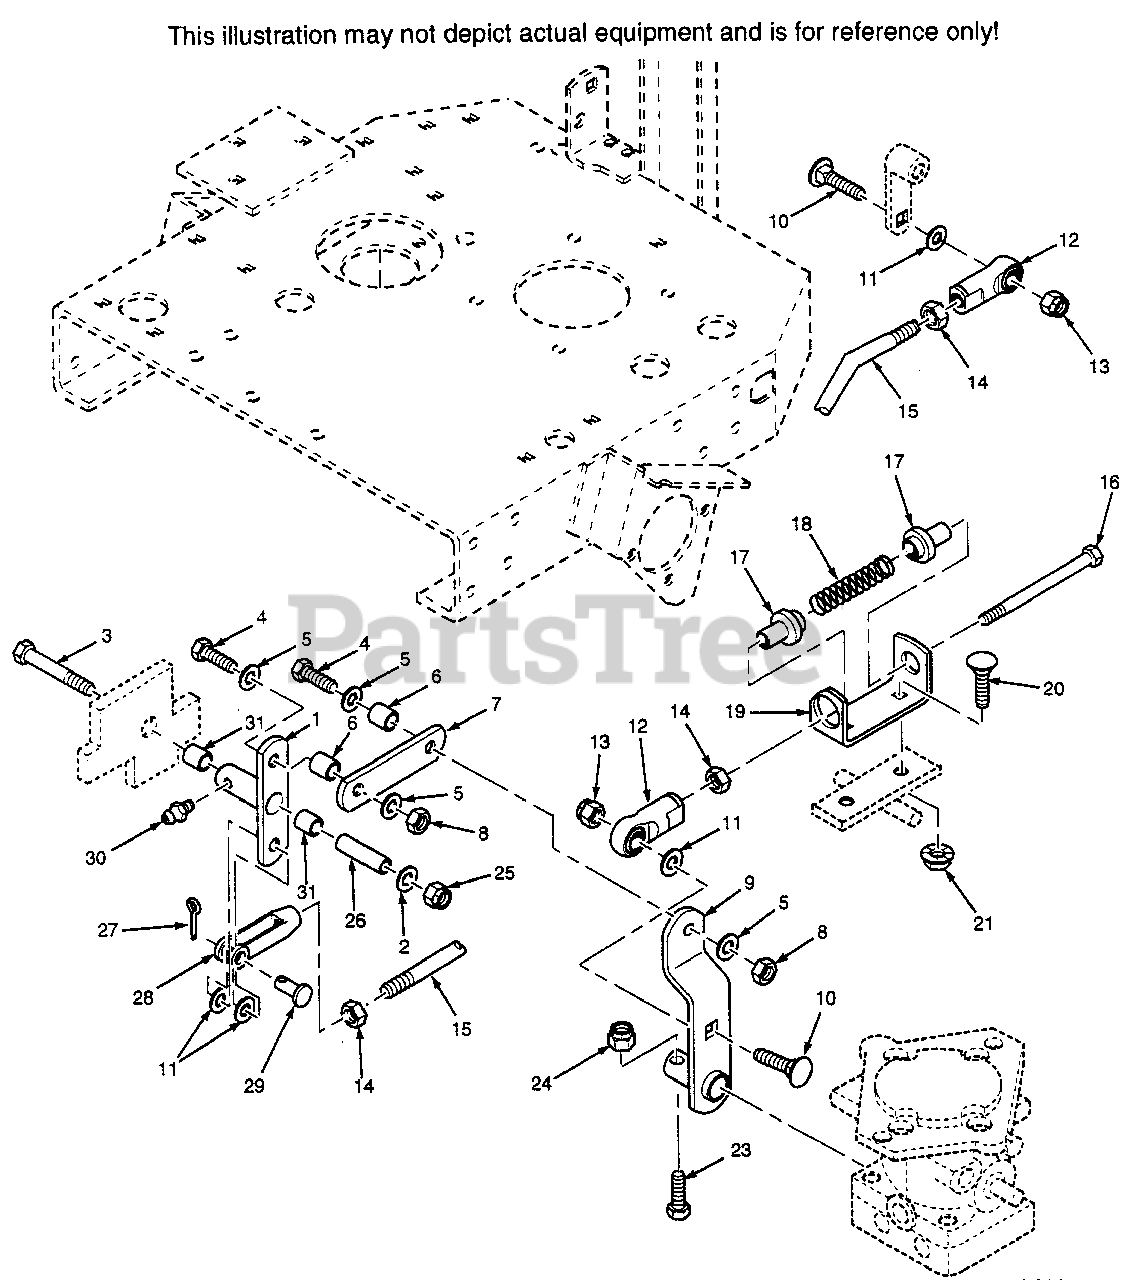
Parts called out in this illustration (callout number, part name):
1	CONTROL LINKAGE, BELLCRANK(INCLUDES 30,31)
2	FLATWASHER, 5/16(.375 X .875 X .083)
3	BOLT, HEX HEAD 5/16-18 X 2-3/4
4	BOLT, HEX HEAD 3/8-16 X 1
5	FLATWASHER, 3/8(.406 X .812 X .065)
6	SLEEVE, PUMP CONTROL LINK
7	LINK, SPEED CONTROL
8	HEX LOCKNUT, 3/8-16
9	CONTROL ARM, PUMP
10	CARRAGE BOLT, RH SH SQNK 3/8-16 X 1-1/2
11	FLATWASHER, 3/8(.391 X .938 X .105)
12	ROD END, RH FEMALE THD 3/8-24
13	HEX LOCKNUT, ELASTIC STOP 3/8-16
14	HEX NUT, 3/8-24
15	CONTROL ROD
16	BOLT HEX HEAD, 3/8-24 X 6-3/4
17	BUSHING, SPRING KEEPER
18	SPRING, NEUTRAL RETURN
19	RETAINER, NEUTRAL SPRING
20	CARRAGE BOLT, 5/16-18 X 1
21	SERR. FL. HEX NUT 5/16-18
23	BOLT, HEX HEAD 1/4-20 X 1-1/4
24	HEX LOCKNUT, ELASTIC STOP 1/4-20
25	HEX LOCKNUT, ELASTIC STOP 5/16-18
26	SLEEVE, CONTROL ARM
27	COTTER PIN, 3/32 X .75
28	CLEVIS, PUMP CONTROL
29	PIN, CLEVIS 3/8
30	GREESE FITTING, 1/4-28 SELF TAP
31	BUSHING, BRONZE
